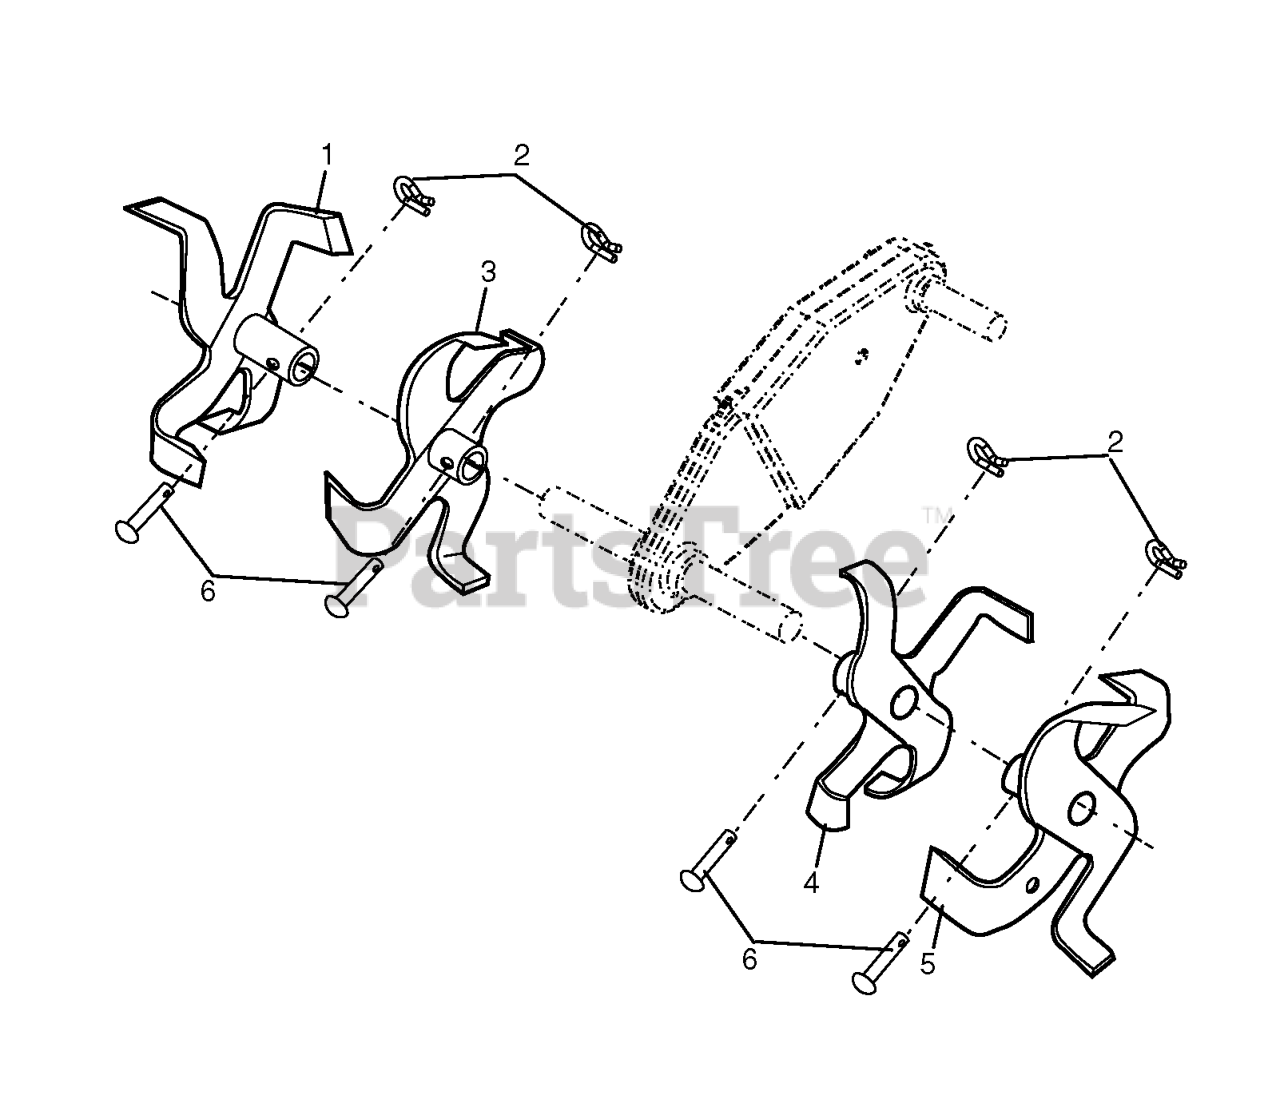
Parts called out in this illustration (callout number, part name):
1	RP TINE
2	SPRING RETAINER
3	RP TINE
4	RP TINE
5	RP TINE
